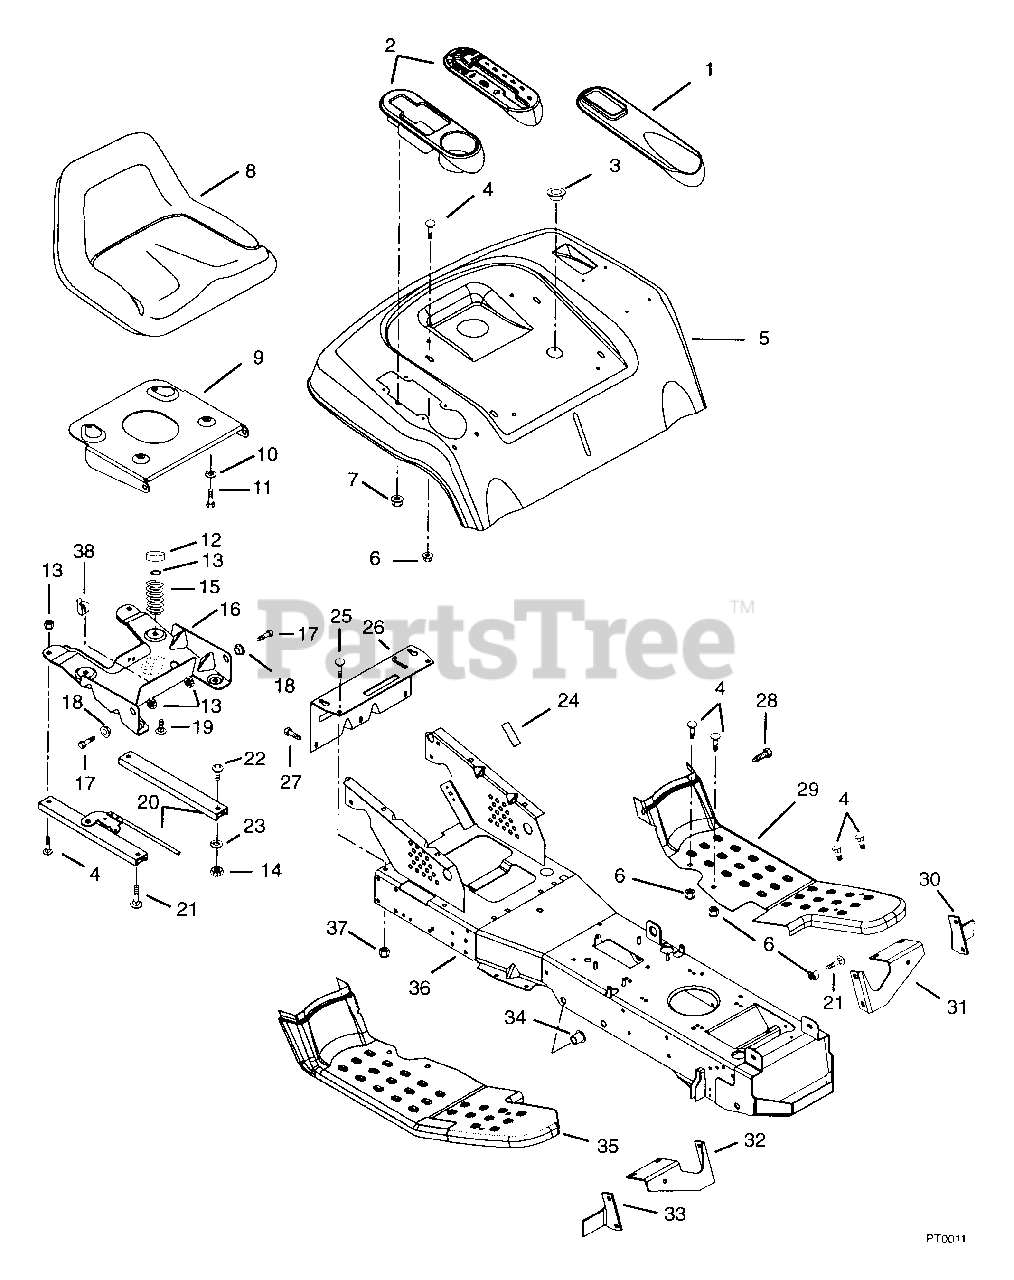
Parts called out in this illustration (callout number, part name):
1	INSERT- LIFT
2	INSERT- SHIFT
2	INSERT - BEVERAGE
3	SNAP BUSHING
4	BLT-RDHDSQNK .312-18X.62SHTPL
5	REAR DECK
6	NUT-FLG. .312-18 PL
7	NUT-SELF-THRDNG FITS.25 STUDPL
8	SEAT- V1400
8	SEAT V-1500 HI WELTLESS
9	SEAT PIVOT PLATE
10	WSHR-LK .312X.097 PL HVY
11	BLT-HEX .31-18X.75 PL GR2
12	TUBE CAP
13	NUT-LK .312-18 GR A PL
14	NUT-HEX .312-18
15	SG-COMP .148X1.23X2.41 WLD87
16	BOX, SEAT
17	BLT-HEX .31-18X.75 PL GR5
18	BSHG-FLG .325X.465X.333X.685
19	BLT-RDHDSQNK.31-18X.75GR5SHTPL
20	SEAT SLIDES -(RAME TAK-3010-4)
21	BLT-RDHDSQNK .31-18X.75 SHT PL
22	SCR-CAP BTHD.31-18X.50 GR5 YZ
23	WSHR-LK-EXT .313X.030 PL
24	PAD,BATTERY
25	BLT-RDHDSQNK .375-16X.75 GR5PL
26	DRAW BAR
27	SCR-TAP .312-18X.75 HWH PL TR
28	SCR-TAP .312-18X.50 HWH PL TR
29	FOOTREST- LH
30	BRACKET - MOWER HEIGHT L.H.
31	BRACE - FOOT REST L.H.
32	BRACE - FOOT REST R.H.
33	BRACKET - MOWER HEIGHT R.H.
34	BSHG-FLG .515X.750X.745X1.00NY
35	FOOTREST- RH HYDRO
35	FOOTREST- R GEAR
36	MAIN FRAME
36	FRAME, MAIN
37	NUT-LK-CTR .375-16 GR A PL
38	CLIP-HARNESS TINNERMAN
